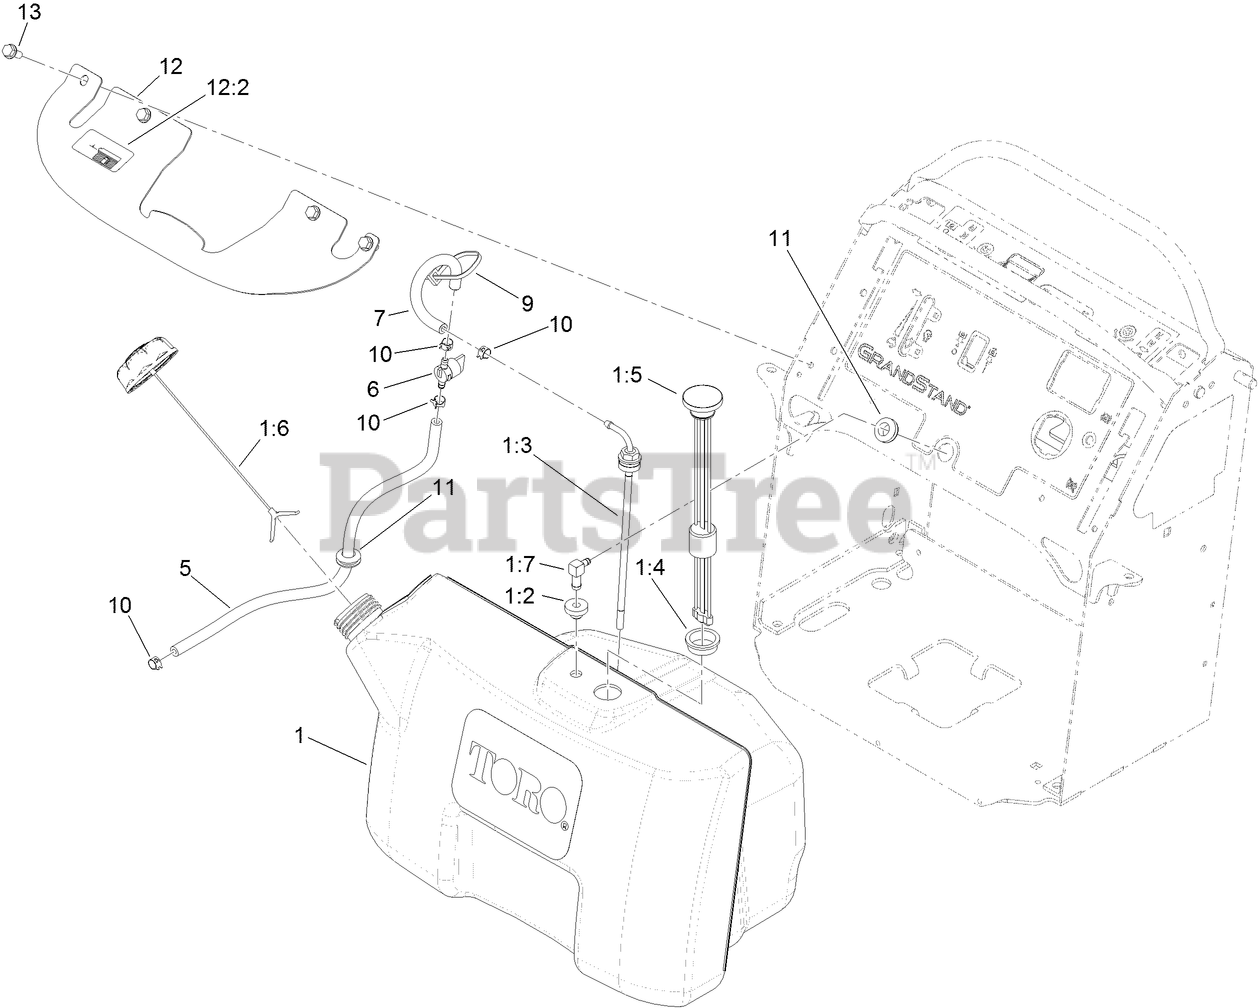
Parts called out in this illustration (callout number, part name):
1	TANK ASM
1:2	BUSHING
1:3	ELBOW-90 DEG
1:4	GROMMET
1:5	GUAGE-FUEL
1:6	CAP-FUEL, RATCHETING
1:7	FITTING-FUEL, BULKHEAD
5	HOSE-FUEL
6	VALVE-FUEL
7	HOSE-FUEL
9	TIE-CABLE
10	CLAMP-HOSE
11	GROMMET
12	BRACKET-TANK
12:2	DECAL-FILL, FUEL
13	SCREW-HWHTF
